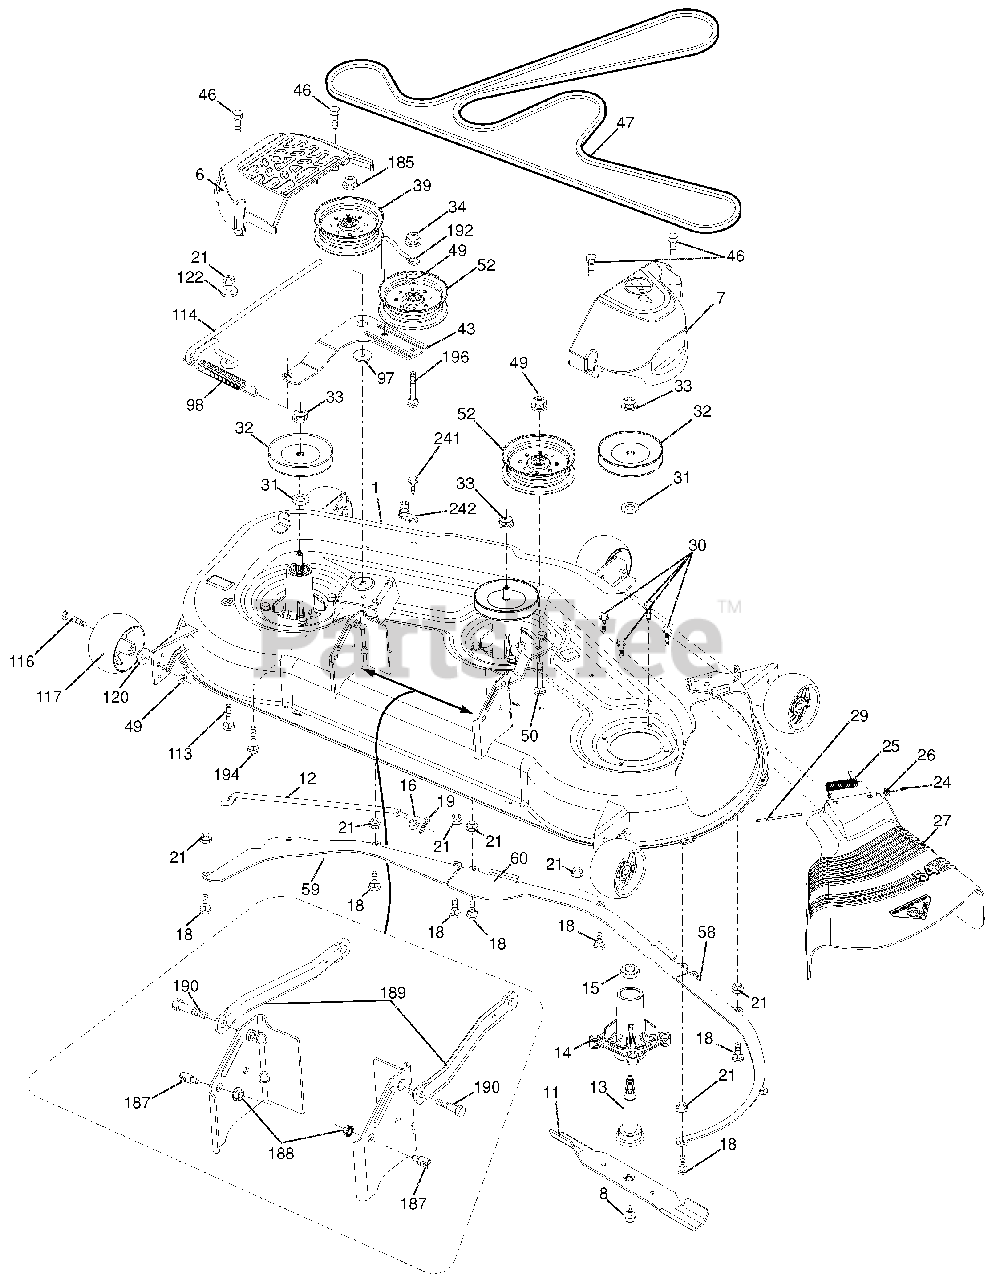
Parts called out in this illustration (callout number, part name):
1	DECK WELDMENT MOWER
6	COVER.MANDREL.LH.54"2006
7	COVER.MANDREL.RH.54"2006
8	BOLT/WASHER ASM.7/16-20.UNF
11	BLADE.BAGGING.54"
12	ROD ANTI-SWAY
13	SHAFT ASM.MANDREL.48/54"SVC
14	HOUSING.MANDREL.4PT.SERVICE
15	BEARING.BALL.MANDREL
16	Washer 13/32 x 13/16 x 12 Ga.
18	BOLT.RDHD.SQNK.5/16-18 X 5/8
19	PIN.COTTER.5/16.BOW TIE LOCK
21	Nut, Hex, Crownlock 5/16-18
24	CAP.SLEEVE..80X.112.BLK.MOWER
25	SPRING.TORSION.48"
26	NUT.PUSH.PHOS.& OIL
27	DEFLECTOR SHIELD
29	ROD.HINGE.42/46"
30	SCREW.THD ROLL.DOD PT.HEX
31	WASHER.SPACER.MANDREL
32	MANDREL.PULLEYS.42,44,50
33	NUT.FLANGE.LOCK.TOP
34	Nut, Hex, Crownlock 3/8-16
39	PULLEY.IDLER.4.50.HUB.SPECIAL
43	ARM.ILDER
46	SCREW.THD.ROLL.1/4-20 X 5/8
47	BELT.DRIVE.54"2006
49	Nut, Hex, Flangelock 3/8-16
50	BOLT.RD.HD.SQ.NK.3/8-16UNC X 2
52	PULLEY.IDLER.4.50.RAW
58	BAFFLE.RIGHT.54"
59	BAFFLE.LEFT.54"
60	BAFFLE.CENTER.54"MOWER
97	WASHER.FLAT.HARDENED
98	SPRING.DRIVE.DECK.2006
113	BOLT.CARR.5/16-18UNC X 1
114	ROD.TENSION.RELIEF
116	BOLT.SHOULDER.3/8-16X3-5/8.GR5
117	WHEEL.GAUGE.RALLY.
120	WASHER.13/32 X 1-1/4 X 12 GA.
122	BUSHING.RELIEF.TENSION
185	NUT.LOCK.FLANGE.7/16-14.GR5
187	STUD.FASTNER.W/'D'ANTI-ROTATIO
188	Nut, Lock Hex Flange 5/16-18 u
189	ARM.SUSPENSION.MOWER.REAR
190	BOLT.SHOULDER
192	KEEPER.BELT.IDLER.54"TL
194	BOLT CARR SQNK 3/8-16 X 2-1/4
196	BOLT.RDHD.SQNK.3/8-16X2-1/2.G5
242	PORT WASHOUT
